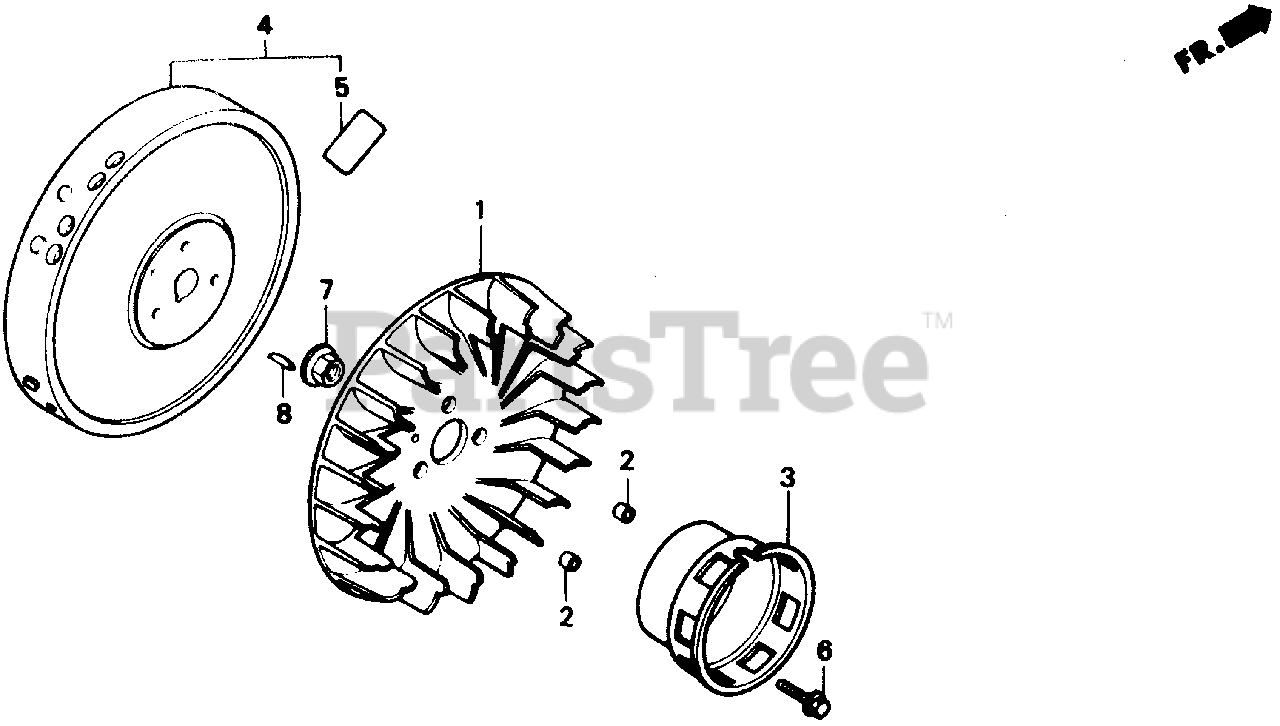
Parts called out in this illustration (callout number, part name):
1	FAN, COOLING
2	COLLAR, FAN
3	PULLEY, STARTER
4	FLYWHEEL (POINT)
4	FLYWHEEL
5	MARK, FLYWHEEL CAUTION
6	BOLT, FLANGE (6X16)
7	NUT, SPECIAL (14MM)
8	KEY, SPECIAL WOODRUFF (25X18)
